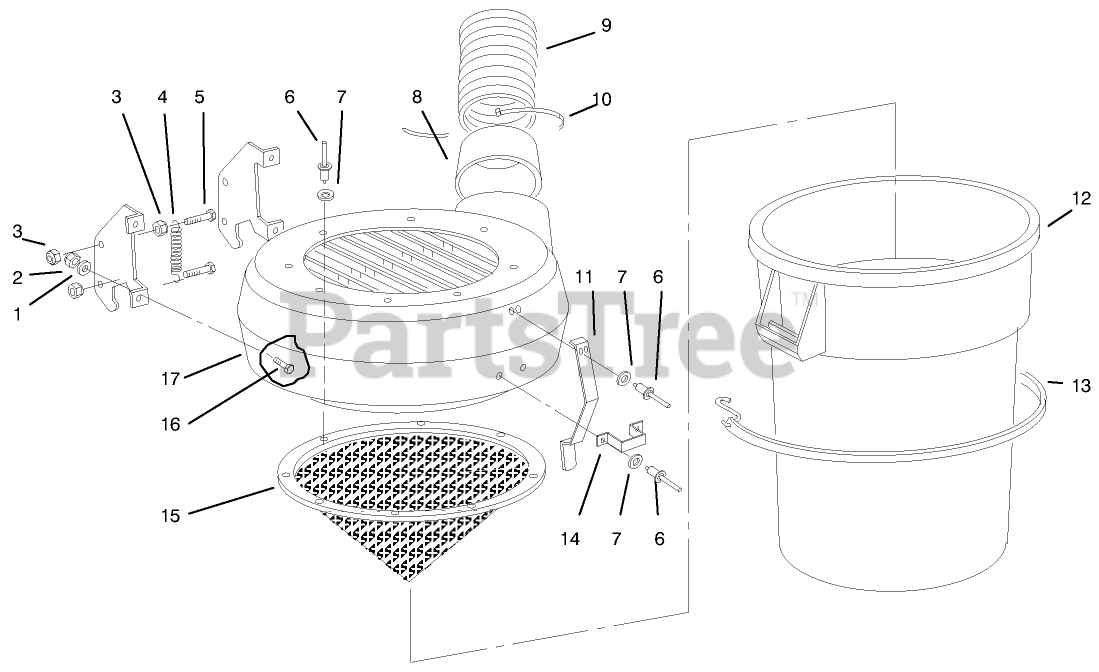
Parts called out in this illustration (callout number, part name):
1	WASHER-PLAIN
2	NUT-LOCK, NI
3	NUT-HEX
4	SPRING-EXTENSION
5	SCREW-HH
6	RIVET-POP
7	WASHER-FLAT
8	SEAL ASSEMBLY NP
9	HOSE 6" X 48"
11	LATCH-BAGGER TOP B
12	CANISTER
13	Strap-Bu nge
14	BRACKET B
15	SCREEN-BAGGER TOP
16	SCREW-HH
17	TOP-CANISTER
